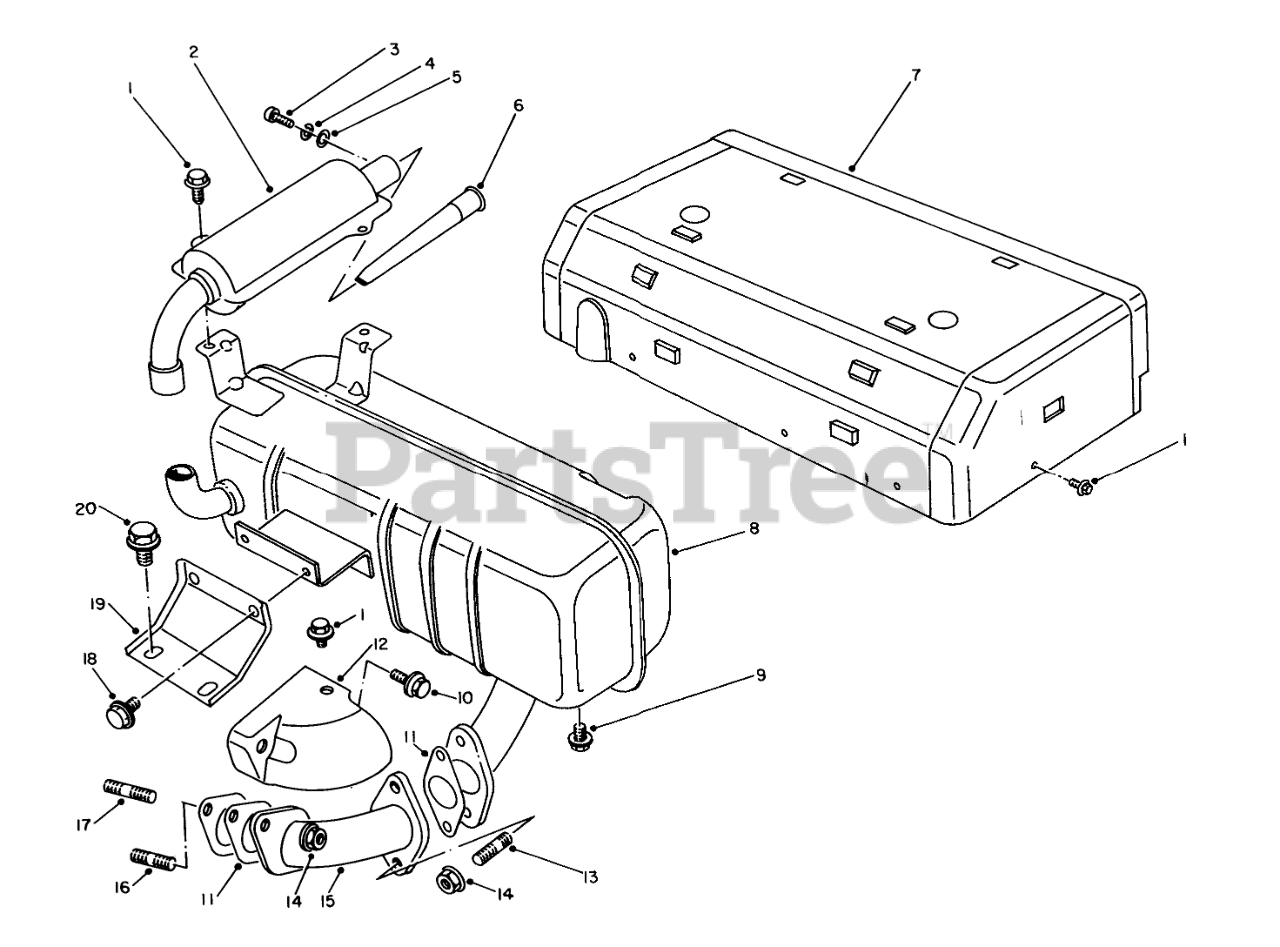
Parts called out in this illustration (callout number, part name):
2	Muffler
4	Lockwasher
5	Washer
6	Screw-Spark Arrester
7	Cover-Muffler
8	Muffler
11	EXHAUST GASKET
12	Cover-Exhaust Pipe
13	Stud Bolt
15	Pipe-Exhaust
16	Stud Bolt
17	Stud Bolt
19	Brace
20	Bolt
